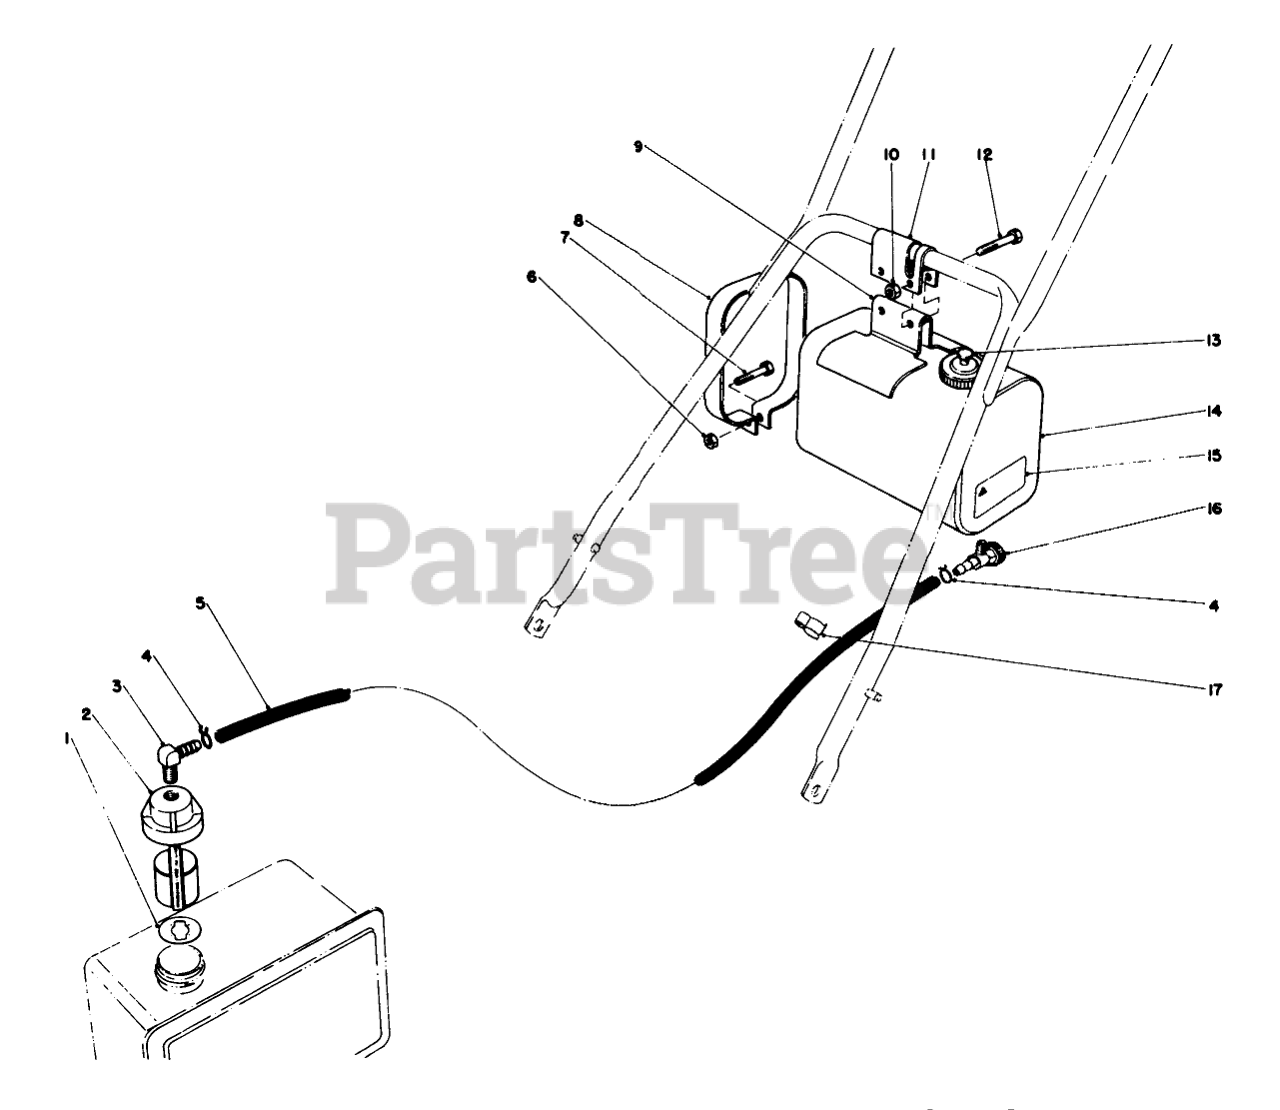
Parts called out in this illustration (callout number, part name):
1	GASKET
2	Fuel Control Valve (Incl. Ref. # 1)
3	CONNECTOR-HOSE
4	Clamp
5	FUEL LINE
6	NUT-LOCK
7	SCREW-HH
8	TANK STRAP
9	FUEL TANK BRACKET
10	Nut
11	Clamp
12	SCREW-HH
14	Fuel Tank (Incl. Ref. #13)
15	Decal-Caution
16	.125 ID SHUTOFF VALVE
17	CLAMP
